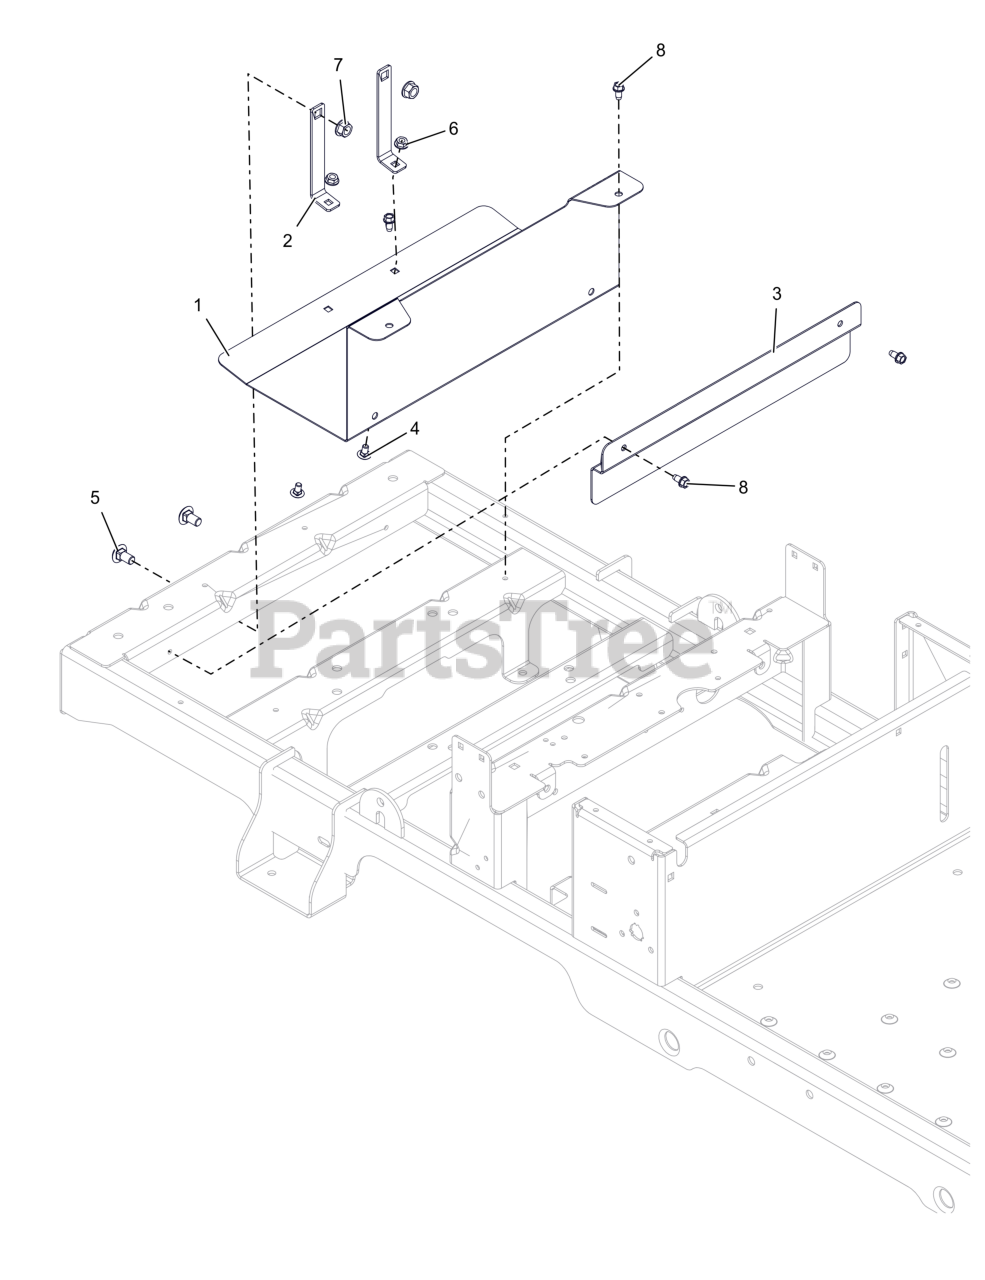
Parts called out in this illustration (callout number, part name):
1	GUARD, HEAT SHIELD (ZOOM/ZT)
2	STRAP, HEAT SHIELD (ZOOM/ZT)
3	GUARD, EXHAUST (BLACK)
4	BLT, RHSN .25-20X.500 G5 ZCC
5	BLT, RHSN .38-16X.750 G5 ZCC
6	NUT-LK-CTR-FLG .25-20 ZC120
7	NUT-LK-CTR-FLG .375-16 GF ZCC
8	SCR-TAP .25-20X.50 HWH ZCC
